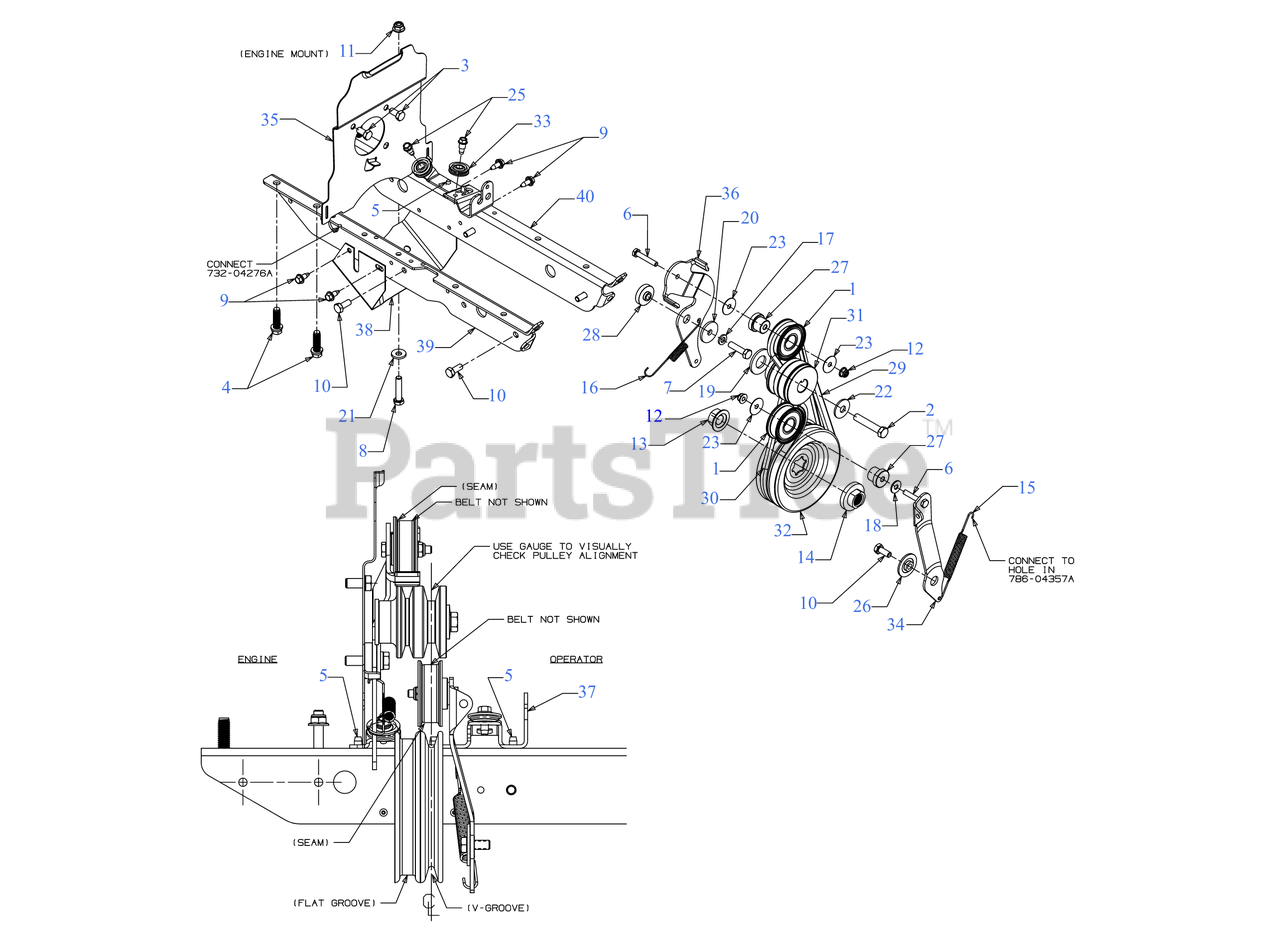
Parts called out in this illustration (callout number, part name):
1	IDLER PULLEY ASSEMBLY
2	HEX SCREW 3/8-24 X2.00
3	HEX SCREW 5/16-24 x .62
4	SCREW 3/8-16 x 1.250
5	SCREW 1/4-20 X.500
6	SCREW 1/4-20 x 1.50 GR.5
7	SCREW 5/16-24 x 1.25 GR5
8	SCREW 5/16-18 x 1.5 LG
9	SCREW 1/4-14 x .625
10	SCREW 5/16-18 x .750
11	FLANGE LOCK NUT 5/16-18
12	FLANGE LOCK NUT
13	FLANGE NUT W/HUB
14	PULLEY HUB
15	RETURN SPRING
16	EXTENSION SPRING
17	LOCK WASHER 5/16
18	FLAT WASHER .28 ID x .74 OD x .063
19	FLAT WASHER
20	WASHER-5/16 x 1.25X 1.27
21	BELLVILLE WASHER .827 x .331 x .098
22	BELL WASHER
23	FLAT WASHER
25	SHOULDER SCREW
26	PIVOT IDLER SPACER
27	SHOULDER SPACER
28	PIVOT IDLER SPACER
29	V-BELT 4L x 25.375
30	V-BELT 3L x 29.125
31	ENGINE PULLEY
32	TRANSMISSION PULLEY
33	CABLE GUIDE ROLLER
34	FORWARD IDLER BRACKET
36	REVERSE IDLER BRACKET
